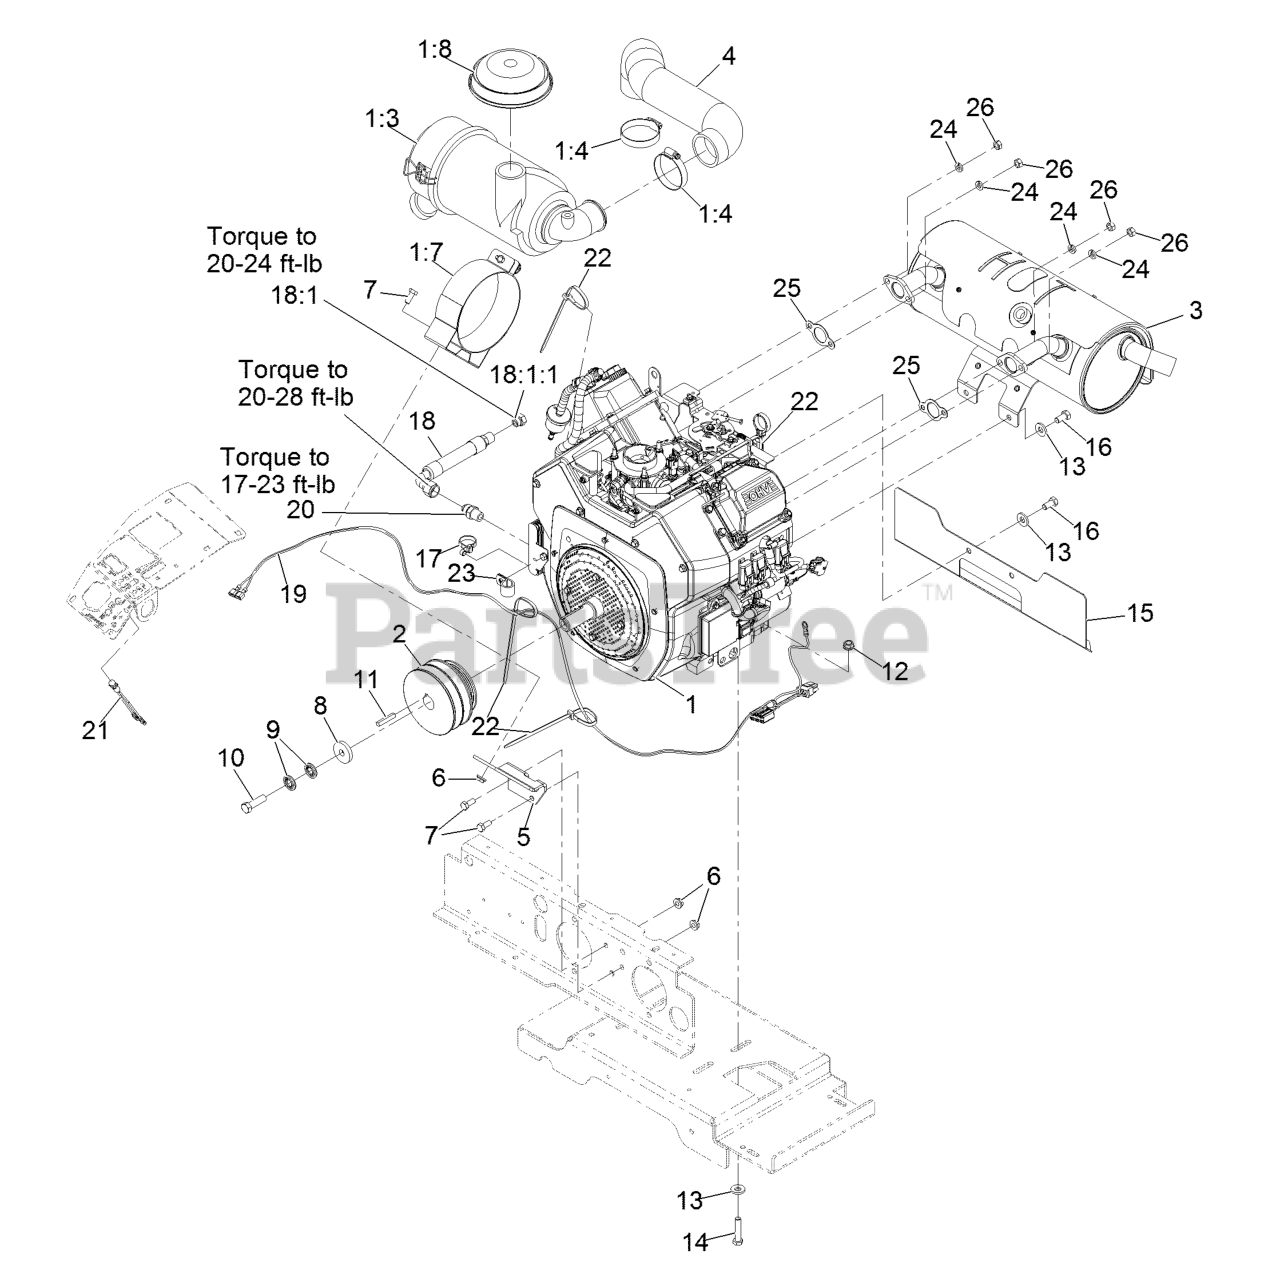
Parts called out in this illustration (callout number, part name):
1	Asm-Engine 730kc Efi
1:3	AIR CLEANER CANISTER ASM
1:4	CLAMP-HOSE
1:7	BRACKET-FILTER, AIR
1:8	HOOD-CLEANER, 2" AIR INTA
3	MUFFLER
4	HOSE-EFI AIR INTAKE
5	BRACKET-FILTER, AIR
7	SCREW-HH
8	WASHER-CLUTCH
9	WASHER-SPRING
10	SCREW-HH
11	KEY-SQUARE
12	NUT-HHF, WHIZ
13	WASHER-BELLEVILLE
14	SCREW-HH
15	SHIELD-EXHAUST
16	SCREW-HH
17	Tie-Cable
18	OIL DRAIN HOSE ASM
18:1	PLUG-HH
18:1:1	O-RING
19	HARNESS-LIGHT INDICATOR (
20	FITTING-STRAIGHT
21	INDICATOR-LED, RED
22	TIE-PLASTIC
23	CLIP-LOOM
24	WASHER-LOCK
26	NUT-HEX
